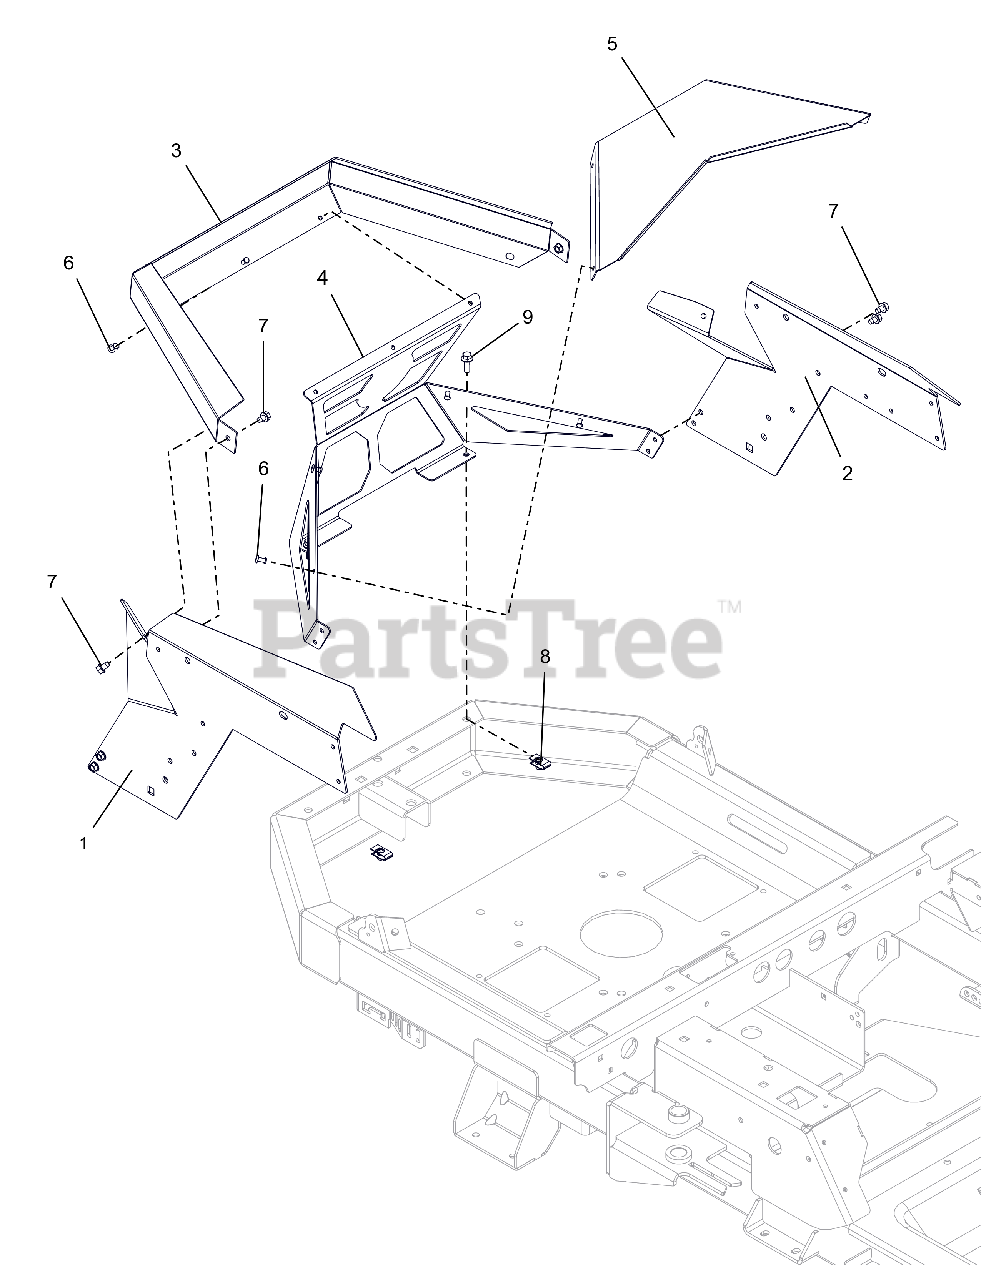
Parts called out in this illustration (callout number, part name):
1	PANEL, RIGHT REAR FENDER MOUNT
2	PANEL, LEFT REAR FENDER MOUNT
3	GUARD, ENGINE WRAP
4	GUARD, ENGINE
5	BAFFLE,ENGINE WRAP
6	RIVET, #66 STEEL POP PD BLACK
7	SCR,TAP .25-20X.375 HWH TR ZCC
8	NUT-RTNR .25-20X.56
9	BLT,HEX-FLG .25-20X.75 G5 BFP
